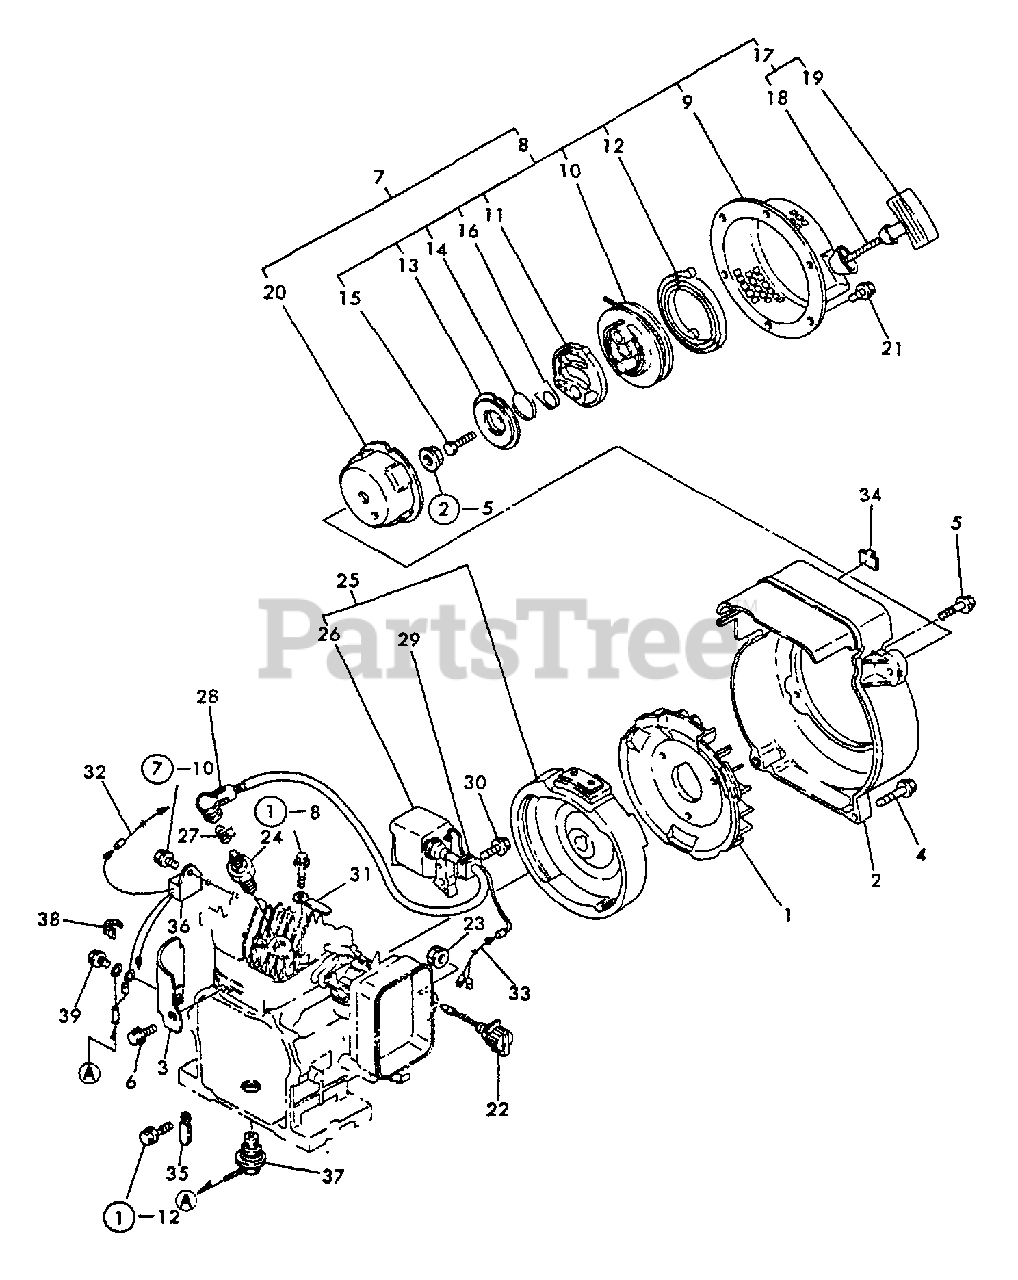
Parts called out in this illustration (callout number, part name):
1	FAN
2	COVER, FAN
3	SHIELD, CYLINDER
4	BOLT - 6×30
5	BOLT - 6×30
6	BOLT - 6×8 -- PLATED
7	STARTER ASSY
8	STARTER ASSY, RECOIL
9	STARTER CASE ASSY
10	PULLEY
11	RATCHET
12	SPRING
13	PLATE, FRICTION
14	SPRING, FRICTION
15	BOLT
16	SPRING, RETURN
17	ROPE ASSY
18	ROPE
19	GRIP, STARTER
20	PULLEY, STARTER
21	BOLT - 6×8 -- PLATED
22	IGNITION SWITCH ASSY
23	U-NUT M8
24	SPARK PLUG - BPM4A
25	FLYWHEEL MAGNETO ASSY
26	COIL, IGNITION
27	TERMINAL, SPARK PLUG CAP
28	CAP, SPARK PLUG
29	GROMMET
30	BOLT - 6×30
31	CLAMP
32	WIRE
33	WIRE
34	CLAMP
35	CLAMP
36	SENSOR UNIT
37	SENSOR, OIL LEVEL
38	CLAMP
39	BOLT - 6×8 -- PLATED
